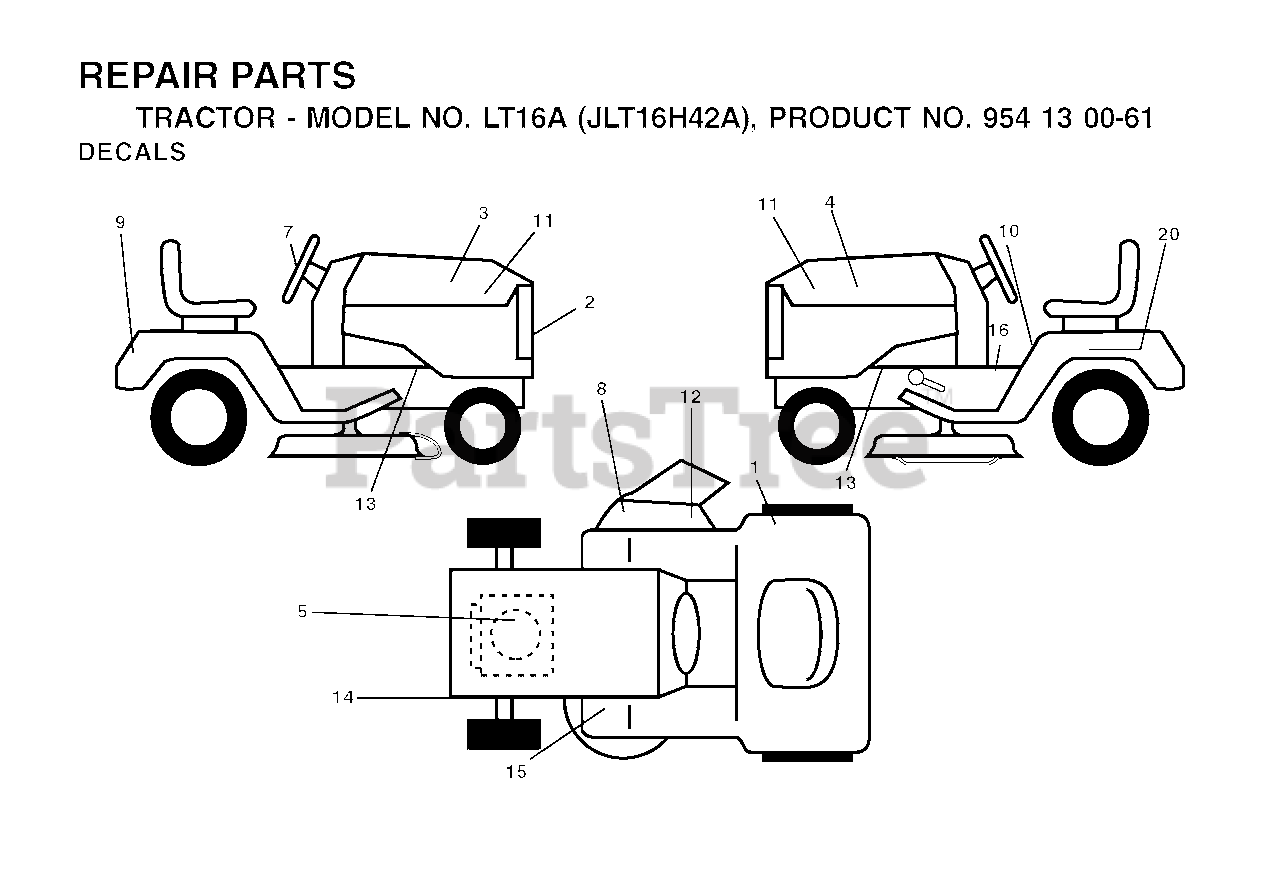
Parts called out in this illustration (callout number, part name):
8	DECAL.INTERNATIONL.CUTFINGER
10	DECAL READ OWNER'S MAN SYMS
12	DECAL DECK "B" 42"
14	DECAL V BELT SCHEMATIC
16	DECAL PARK BRAKE
20	DECAL BTRY SYMBOLS
